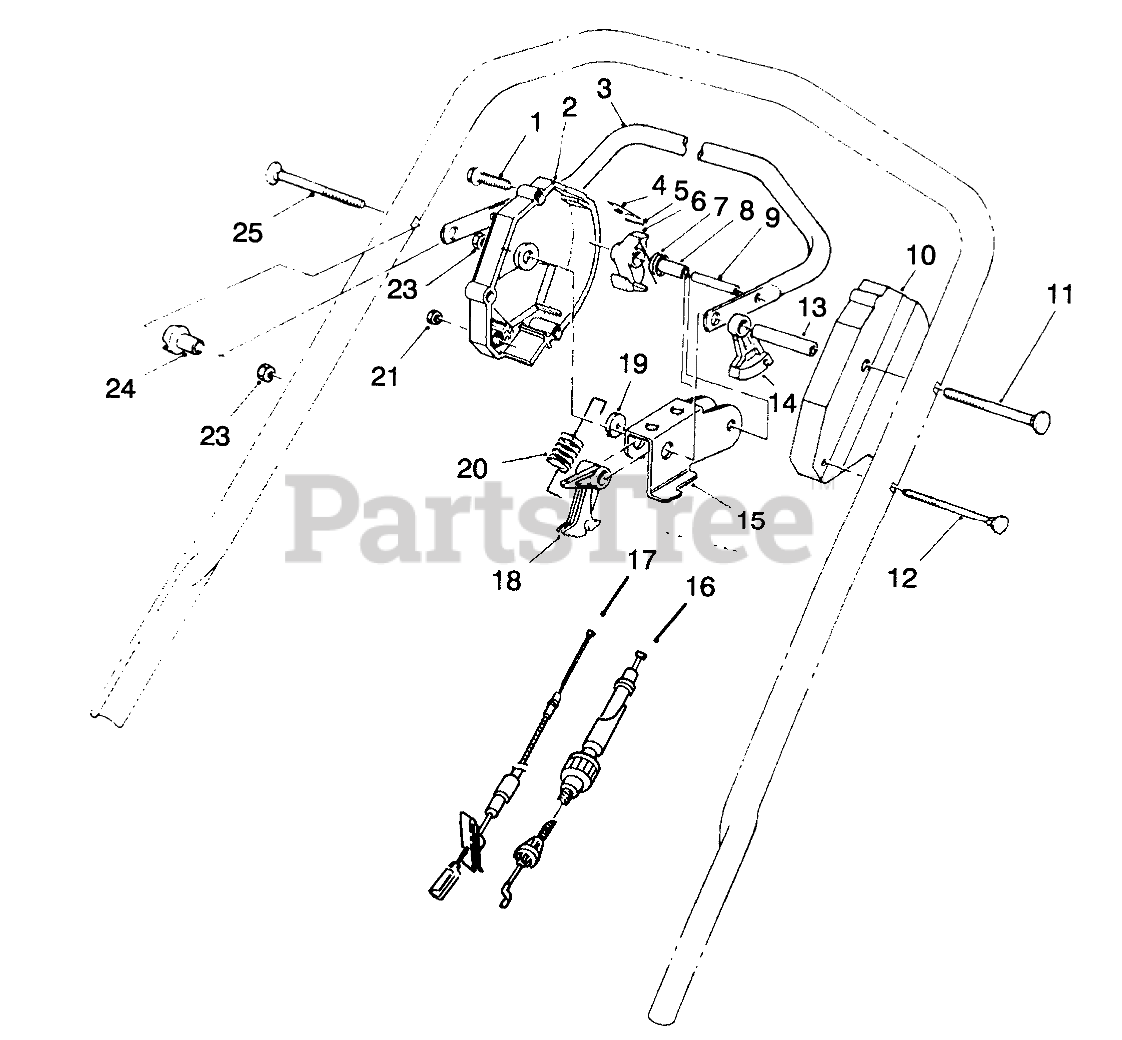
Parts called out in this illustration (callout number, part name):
1	SCREW-HWHTF
2	Housing-Control
3	Bar-Control
4	SPRING-LEAF
5	PIN-INSERT
6	HOOK-CONTROL
7	SPRING-TORSION
8	SPACER
9	PIN-ROLL, SLOTTED
10	HOUSING-CONTROL, LH
11	Screw-Handle
12	HANDLE SCREW
13	TUBING-SPACER
14	LEVER-TRACTION
15	ROCKER
16	TRACTION CABLE
17	BBC CABLE ASSEMBLY
18	LEVER-CABLE
19	WASHER-NYLON
20	SPRING-DETENT
21	NUT-HEX
23	Nut-Lock
24	SPACER-SUPPORT
25	SCREW-HANDLE
